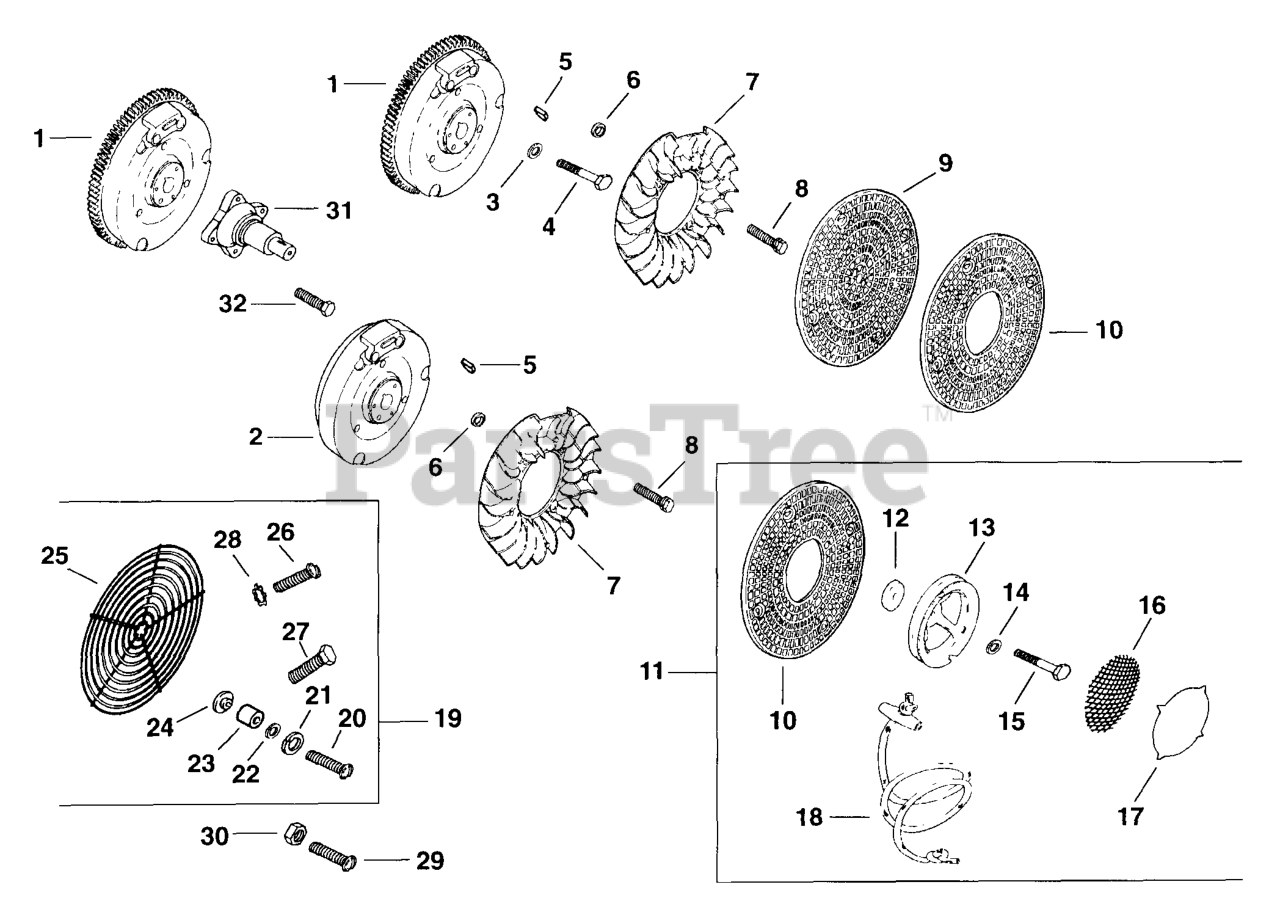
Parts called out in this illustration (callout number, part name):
1	FLYWHEEL - DISCONTINUED
3	WASHER (KM)-USE 12 468 03-S
4	SCREW, MACH 3/8-24X1-1/4"
5	KEY, 3/16" X 1"
8	SCREW, WSH HD 1/4-20X5/8" - DISCONTINUED
9	SCREEN, GRASS
